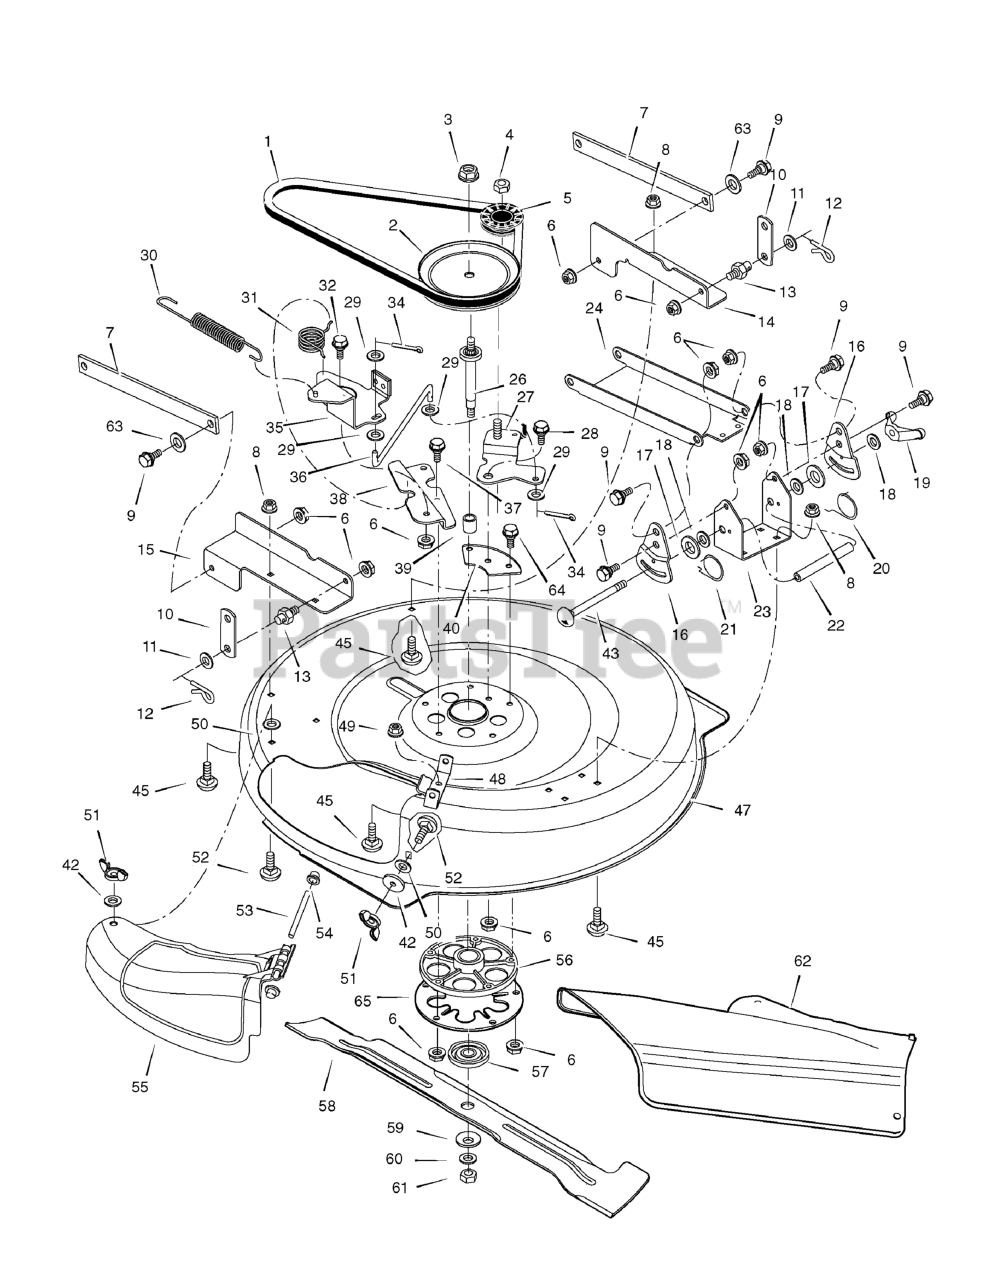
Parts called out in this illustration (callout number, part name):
1	Belt, Blade Drive
2	Pulley, Input
3	Locknut
4	Nut, Flange
5	Pulley, Idler
6	Nut, Flange
8	Nut, Flange
9	Bolt, Shoulder
11	Washer
12	Pin, Hair
13	Pin, Threaded Shoulder
14	Bracket, Left Rear
15	Bracket, Right Rear
16	Plate, Adjustment
17	Pad, Friction
19	Wingnut
20	Spring, Left Torsion
21	Spring, Right Torsion
22	Tube, Spacer
23	Bracket, Deck
24	Hanger, Front
26	Shaft, Splined
27	Arm Assembly , Idler
28	Bolt, Shoulder
29	Washer
30	Spring, Extension
31	Spring, Torsion
32	Bolt, Shoulder
34	Pin, Cotter
35	Arm Assembly, Brake
36	Link, Idler Arm
37	Bolt
38	Bracket, Brake Mounting
39	Spacer, Jackshaft
40	Z Plate, Idler Mounting
43	Bolt, Carriage
45	Bolt, Carriage
47	Housing, Blade
48	Hinge, Mulching Cover
49	Nut, Flange
50	Nut, Speed
51	Wingnut
52	Bolt, Carriage
53	Rod, Chute Deflector
54	Cap, Push
55	Cover, Mulch
56	Mandrel Housing
57	Adapter, Blade
59	Washer, Cup
61	Nut, Blade Mount
62	Deflector, Chute
65	Plate, Jackshaft Support
